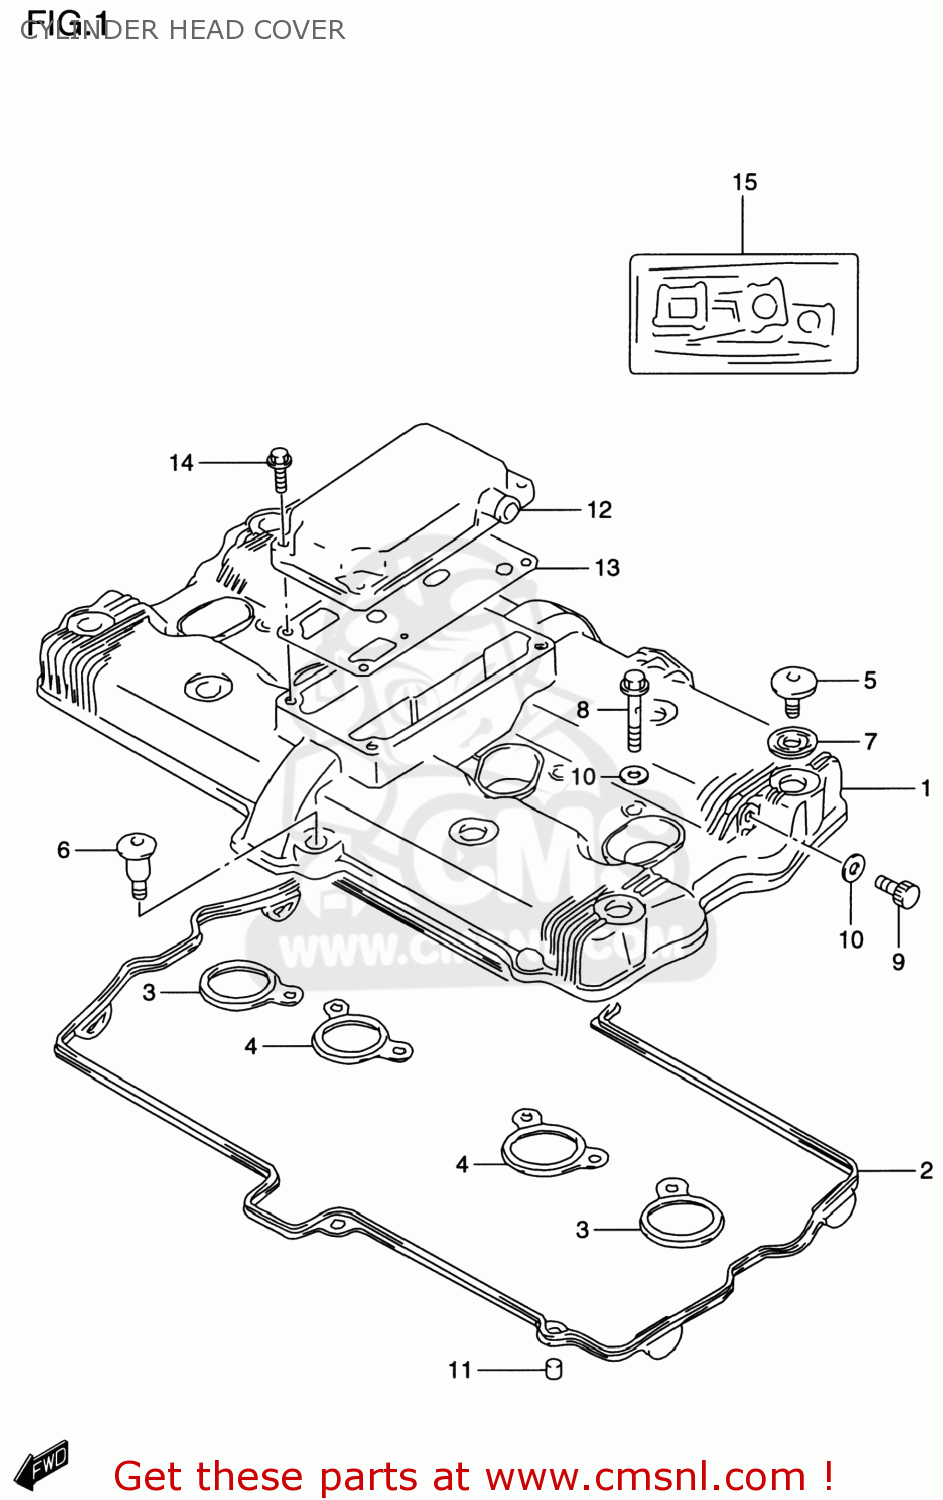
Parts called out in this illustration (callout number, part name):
1	COVER,CYLINDER HEAD
2	GASKET,CYLINDER HEAD COVER (NAS)
3	GASKET,HEAD COVER NO.2 (NAS)
4	GASKET,HEAD COVER NO.3 (NAS)
5	BOLT(7X17.5)
6	BOLT(7X31)
7	WASHER(10.6X25.5X2.3)
8	BOLT,UNION 8X35
9	PLUG
10	GASKET 8.2X14X1 (NAS)
11	PIN
12	COVER,BREATHER
13	GASKET,BREATHER COVER
14	BOLT
15	GASKET SET (NAS)
